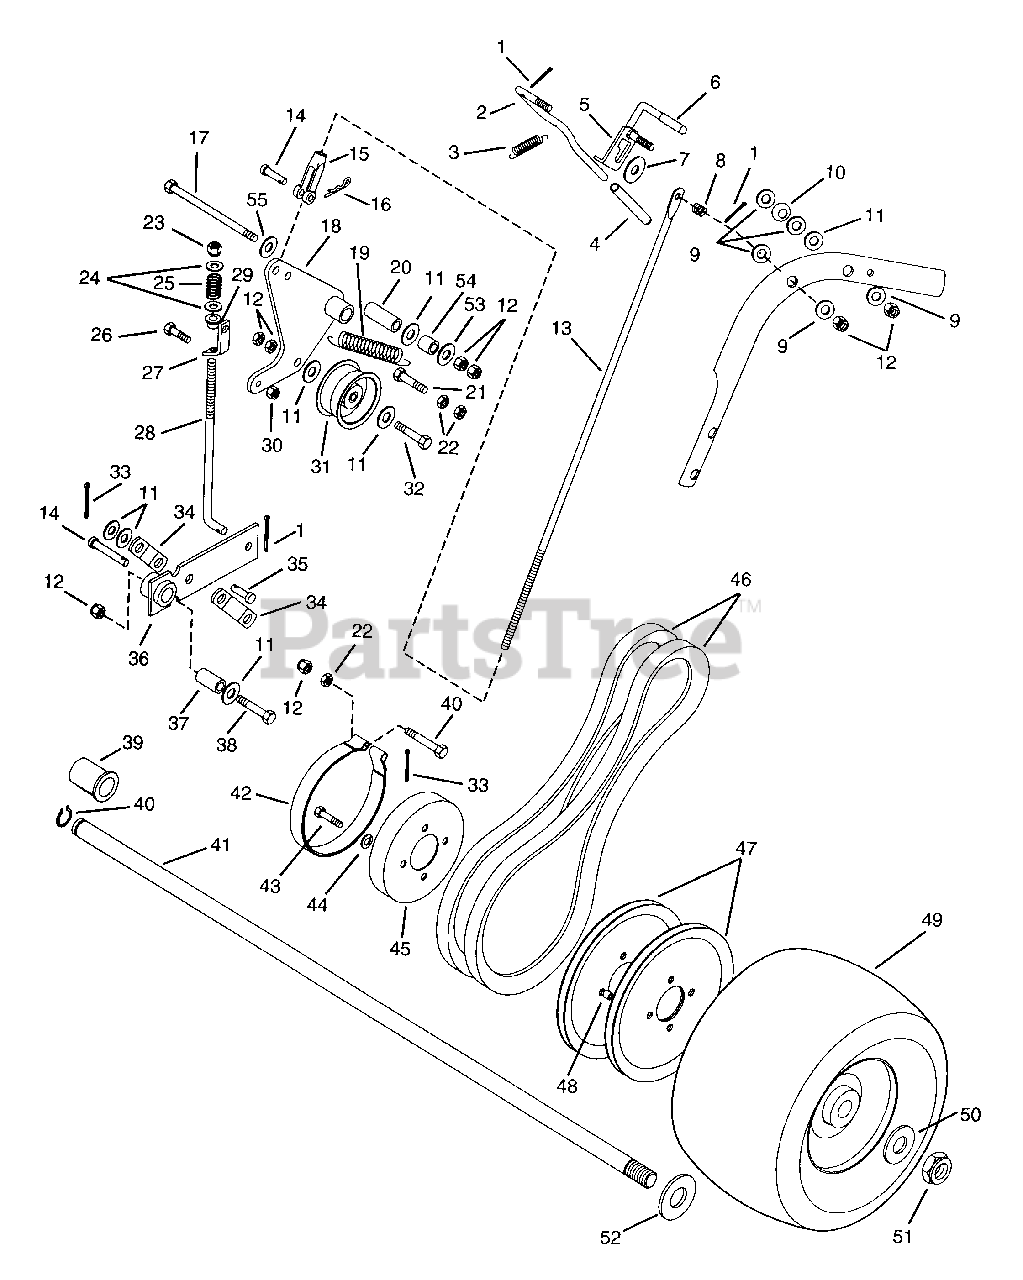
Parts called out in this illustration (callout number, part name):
1	@PIN-CTR .09X.75 EXTPRSQCT YWZ
2	LEVER, HAND CONTROL LH
3	SG-TENS .041X.500X1.750
4	GRIP,HAND CLUTCH LEVER
5	WLDMT,CLUTCH-BRAKE LOCK
6	TIP - BRAKE LOCK LEVER
7	WSHR-FL-STL .406X1.375X.135 YZ
8	SG-COMP .045X.600X.750 WLD7.5
9	WSHR-FL-NY .375X.75X.060
10	SPRING WASHER
11	@WSHR-FL-STL.406X.812X.065 YWZ
12	@NUT-LK-CTR .38-16 YWZC
13	ROD,CLUTCH ACTUATING
14	PIN-CLEV .38X1.25 YWZC
15	CLEVIS, .38-24 ADJ.
16	PIN-HAIR INT .08X.18X1.18 YWZC
17	@BLT-HEX .38-16X4.00 GR5 YWZC
18	WLDMT,WHL CLUTCH ARM
19	SG-TENS .069X.62X3.50 WLD20
20	BUSH.,S.385X.610X1.80 ST
21	@BLT-HEX .38-16X1.50 GR5 YWZC
22	@NUT-HEX .31-18 YWZC
23	@NUT-LK-CTR .31-18 YWZC
24	@WSHR-FL-STL.344X.688X.065YWZC
25	SG-COMP .125X.78X1.00 YWZ
26	@BLT-HEX .25-20X.75 GR5 YWZC
27	L-BKT, PRO BRAKE LINK
28	ROD,BRAKE
29	BSHG-FLG .320X.620X.312 NY
30	@NUT-LK-CTR .25-20 YWZC
31	IDLER 2.75X1.25
32	@BLT-HEX .31-18X2.25 GR5 YWZC
33	@PIN-CTR .12X.75 EXTPRSQCT YWZ
34	LINK,BRAKE ARM
35	PIN-CLEV .38X.75 YWZC
36	WLDMT,BRAKE ARM
37	BUSH.,S.391X.622X.950 ST
38	@BLT-HEX .38-16X2.00 GR5 YWZC
39	BSHG-FLG 1.010X1.38X1.4X1.65
40	RG-RTNG-EXT 1.00X.078
41	AXLE SHAFT, PRO-150
42	ASM, BRAKE BAND, PRO
43	@BLT-HEX .31-18X1.50 GR5 YWZC
44	@WSHR-LK .31X.078 REG YWZC
45	DRUM,BRAKE
46	V-BELT, HA-COGGED (SET)
47	PLY-V 9.00X3.75
48	BUSH.,S.385X.625X.475 ST
49	TIRE/WHEEL ASSY, 13X6.50-6
50	WSHR-FL-STL 1.010X1.505X.062YZ
51	@NUT-LK-CTR .44-14 YWZC
52	WSHR-THRST 1.55X1.002X.093
53	WSHR-FL-STL .328X.87X.179 YWZC
54	BSHG-SLV .391X.688X.52 PM
55	WSHR-FL-STL.44X1.625X.315 YWZC
